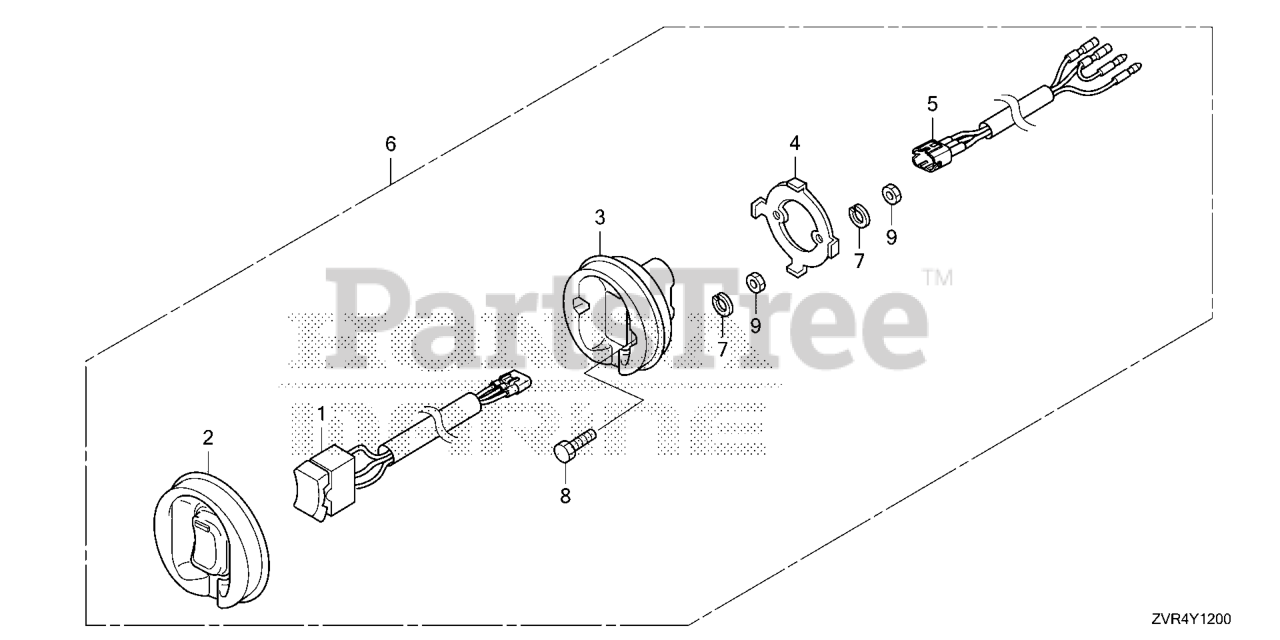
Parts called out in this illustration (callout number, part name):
1	SWITCH ASSY., TROLLING CONTROL (ENGINE NO.)
2	RUBBER, TROLLING CONTROL SWITCH PANEL (ENGINE NO.)
3	BODY, TROLLING CONTROL SWITCH PANEL (ENGINE NO.)
4	BRACKET, TROLLING CONTROL SWITCH PANEL (ENGINE NO.)
5	HARNESS, TROLLING CONTROL SWITCH PANEL (ENGINE NO.)
6	PANEL ASSY.
7	*90504-ZZ5-M00
8	BOLT, HEX. (4X20) (ENGINE NO.)
9	NUT, HEX. (4MM) (ENGINE NO.) (NOT AVAILABLE)
